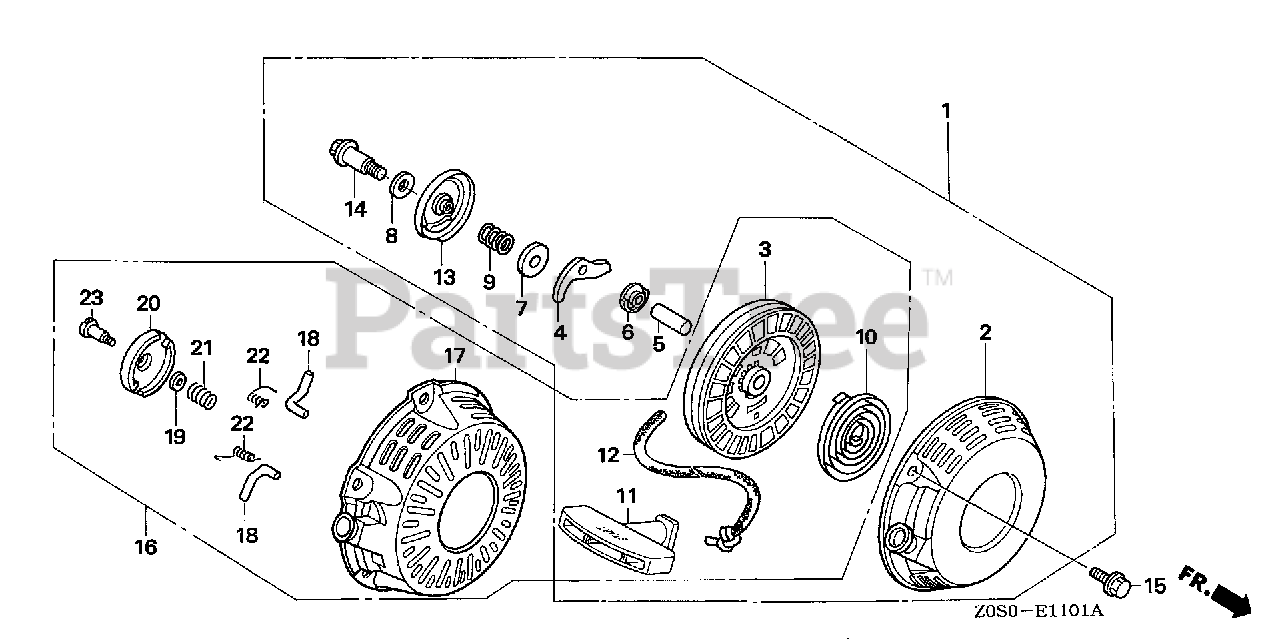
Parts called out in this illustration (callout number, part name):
1	STARTER ASSY., RECOIL *R280* (POWER RED)
2	CASE, STARTER *R280* (POWER RED)
3	REEL, RECOIL STARTER (BLACK)
3	REEL, STARTER
4	RATCHET, STARTER
5	SHAFT, RATCHET
6	PLATE
7	PLATE A, FRICTION
8	PLATE B, FRICTION
9	SPRING, FRICTION
10	SPRING, RECOIL STARTER
10	SPRING, STARTER RETURN
11	GRIP, STARTER
11	KNOB, RECOIL SRARTER
12	ROPE, RECOIL STARTER
13	COVER, STARTER REEL
14	BOLT, REEL COVER
15	BOLT, FLANGE (6X10)
16	STARTER ASSY., RECOIL *R280* (POWER RED)
17	CASE, RECOIL STARTER *R280* (POWER RED)
18	RATCHET, STARTER
19	PLATE, FRICTION
20	GUIDE, RATCHET
21	SPRING, FRICTION
22	SPRING, RETURN
23	SCREW, SETTING
